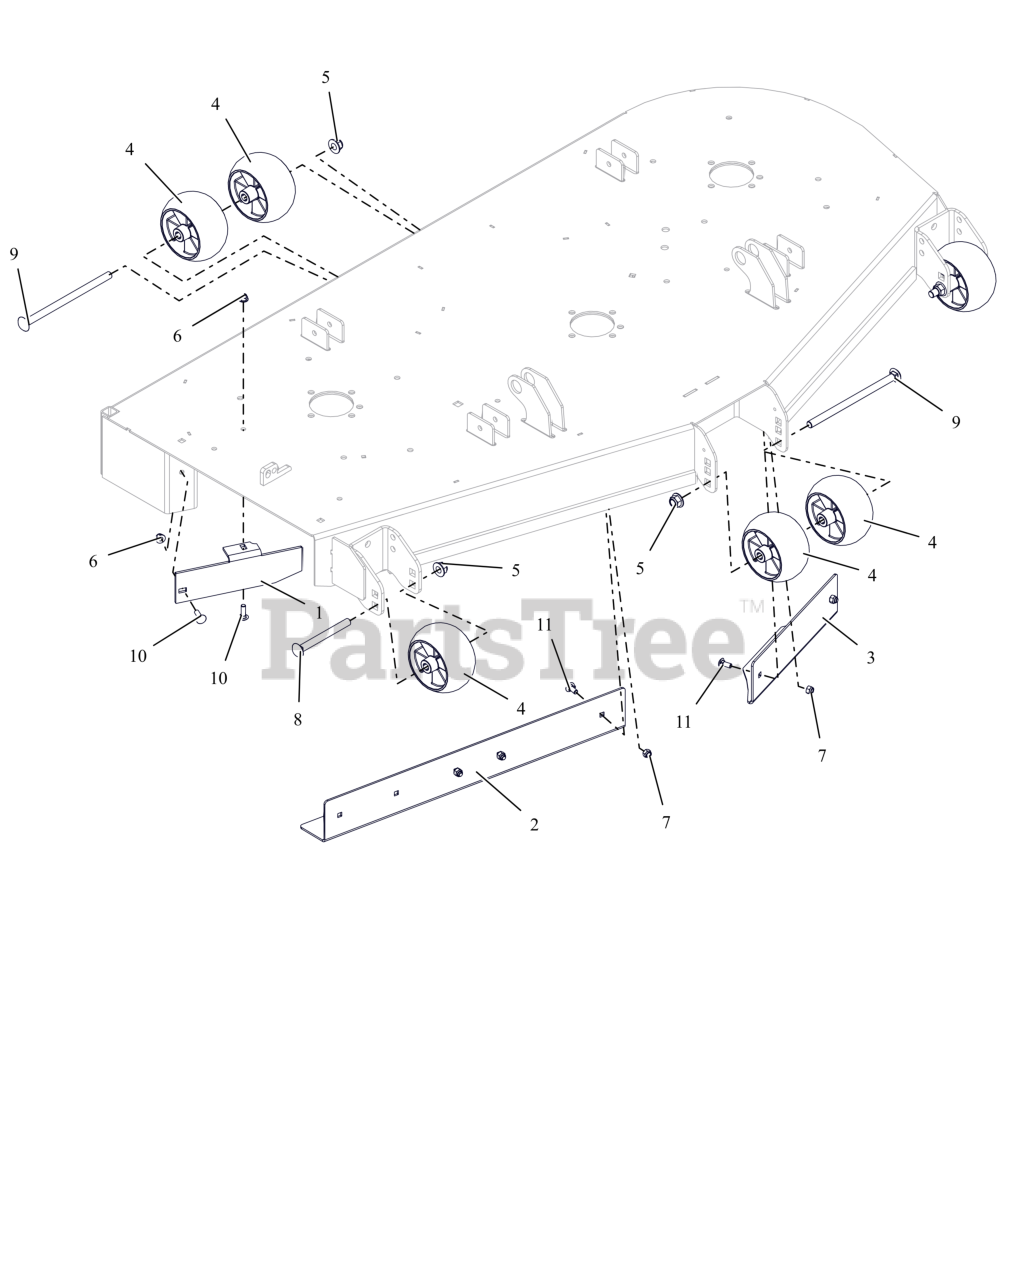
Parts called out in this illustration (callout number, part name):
1	60" DISCHARGE BAFFLE - RED
2	BAFFLE, 60" RH VACUUM (RED)
3	BAFFLE, 60" LH VACUUM (RED)
4	WHEEL, ANTI SCALP - 5X3 CTR W/RIBS
5	NUT,NYL-FLG .50-13 GF ZCC
6	NUT,NYL-FLG .31-18 GF ZCC
7	NUT,NYL .31-18 G5 ZCC
8	BLT, RHSN .50-13X5.00 G5 ZCC
9	BTL,RHSN .500-13 X 8.5S G5 ZCC
10	BLT,RHSN .31-18X1.00 G5 ZCC
11	BLT,RHSN .31-18X.75 G5 ZCC
